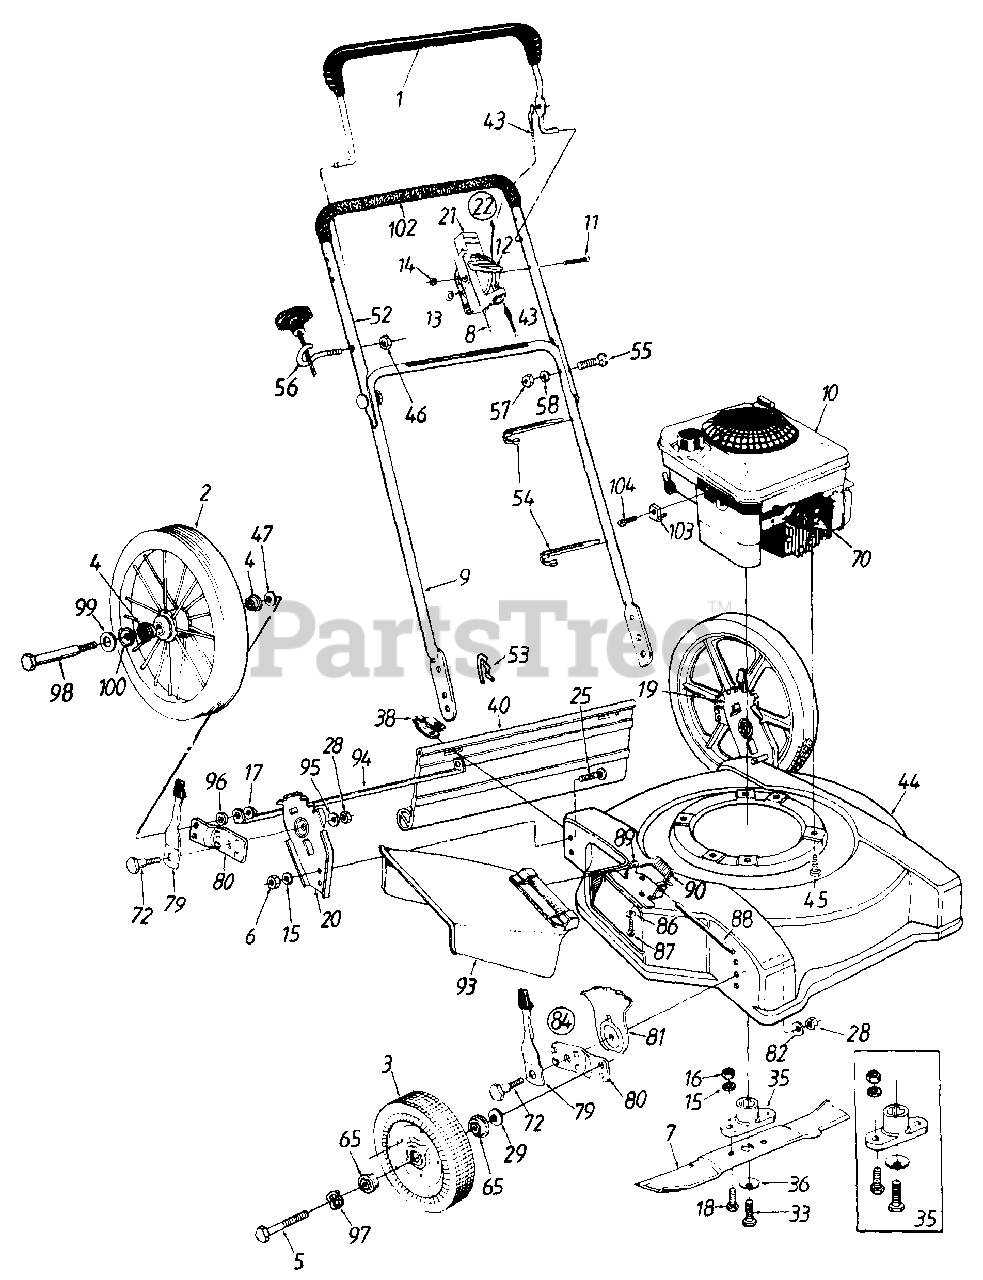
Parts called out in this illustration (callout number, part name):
1	Control Handle
2	16" Rear Wheel Ass'y. (Steel)
3	8" Front Wheel Ass'y. (Steel)
4	Ball Bearing 1/2" I.D.
5	Front Axle Bolt
6	Hex Nut 3/8-24 Thd. (Gr. 8)
7	22" Blade
8	Throttle Control Wire 51" Lg.
9	Lower Handle
10	Engine
11	Oval C-Sunk Mach. Scr.
12	Throttle Lever
13	Spr. Wash. .66" I.D.
14	Hex L-Nut 1/4-20 Thd.
15	L-Wash. 3/8" I.D.
16	Hex Nut 3/8-24 Thd.
17	Flange L-Nut 3/8-18 Thd.
18	Hex Bolt 3/8-24 x 1.0" Lg.
19	Wheel Brkt. Ass'y. - L.H.
20	Wheel Brkt. Ass'y. - R.H.
21	Throttle Body
22	Throttle Box Comp.
25	Ribbed Neck Bolt 3/8-24 x .80"
28	Hex Nut 3/8-16 Thd.
29	Bell-Wash. .400" I.D. x .88"
33	Hex Bolt 3/8-24 x 1.5" Lg.
35	Blade Adapter Kit
36	Bell-Wash. .39" I.D.
38	Hinge Clip
40	Rear Flap Ass'y.
43	Control Cable - 39"
44	22" Deck Ass'y.
45	Hex Wash. Hd. TT-Tap Scr. 3/8-16 x 1.00" Lg.
46	Hex Nylon L-Nut 1/4-20 Thd.
47	Bell-Wash. .38" I.D. x .88"
54	Cable Tie
55	Curved Carriage Bolt 5/16-18 x 1.38" Lg.
57	Hex Nut 5/16-18 Thd.
58	L-Wash. 5/16" I.D.
65	Ball Bearing
70	Spark Plug Boot
72	Shoulder Bolt .50" Dia.
79	Spring Lever Ass'y. w/Knob
81	Height Adj. Plate
82	Bell-Wash. .39" I.D. x 1.38"
84	Front Height Adj. Ass'y. Comp. - R.H.
86	Bell-Wash. .285" I.D. x .75"
87	Hex Wash. Hd. Tap Scr. 1/4-20 x .5" Lg.
88	Hinge Pin
89	Adapter Plate
90	Torsion Spring
93	Chute Deflector Ass'y. Comp.
96	Spacer .503" I.D. x .75"
97	Wave Washer .53" I.D.
98	Rear Axle Bolt
99	Fl-Wash. .51" I.D. x 1.372"
100	Spr. Wash. .5" I.D. x 1.0"
102	Foam Grip
103	Casing Clamp
104	Hex Wash. Hd. Tap Scr. #10-32 x .62" Lg.
